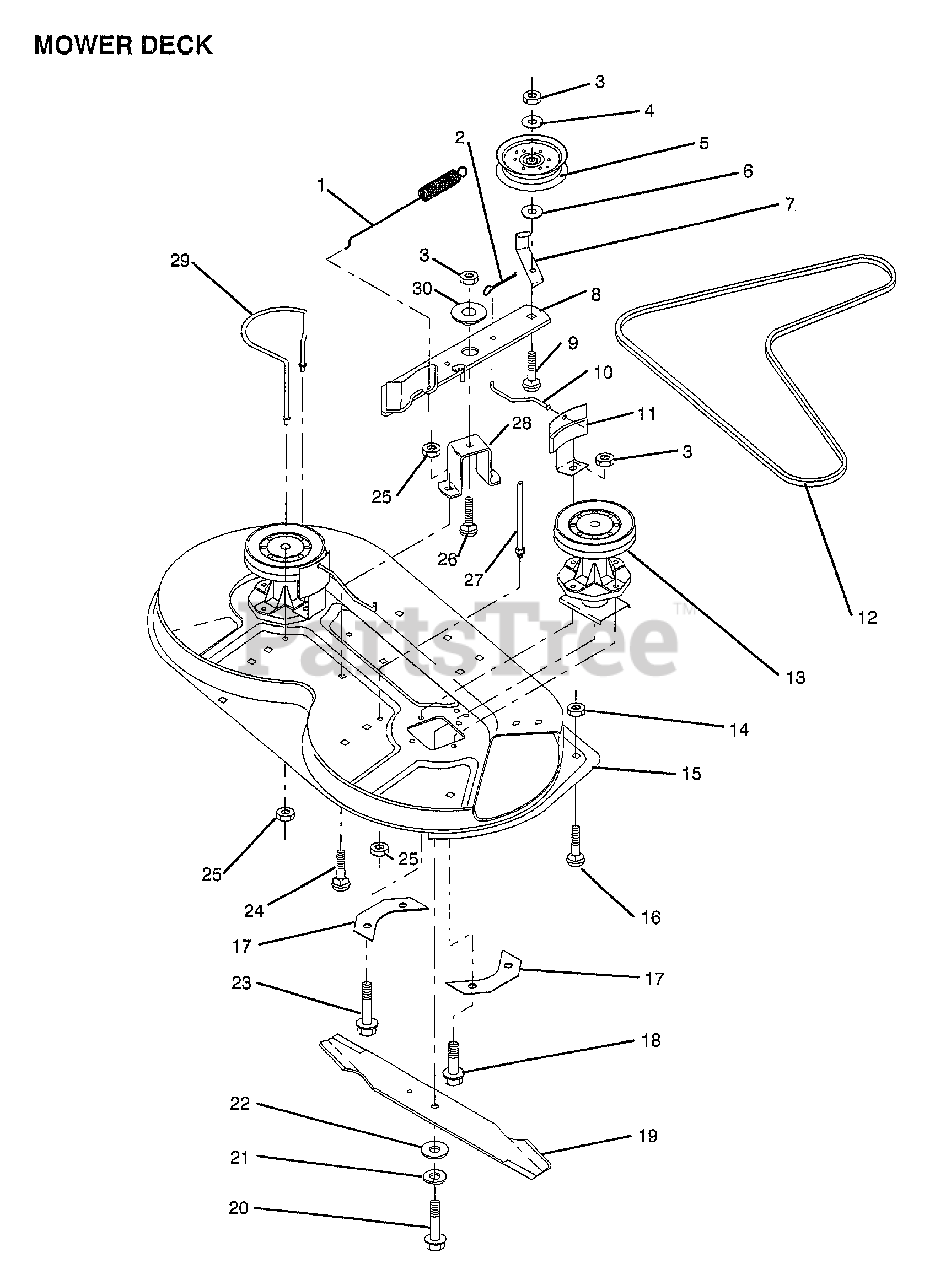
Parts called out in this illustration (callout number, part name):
4	WASHER
5	PULLEY IDLER
6	WASHER GT
8	IDLER ARM ASS'Y
9	BOLT CARRIAGE
10	ROD BRAKE
11	BRAKE LT
12	BELT.MOWER.79.75
13	MANDREL ASS'Y
16	BOLT
17	SUPPORT PLATE LT
18	SCREW
19	"BLADE.36""HIGH LIF"
20	BOLT.3/8-24X1-1/2
22	WASHER
23	SCREW
24	BOLT
26	BOLT D
27	"GUIDE,REAR BEL RH"
28	"SUPT,IDLER ARM"
29	GUIDE BELT LH
30	SPACER RETAINER
